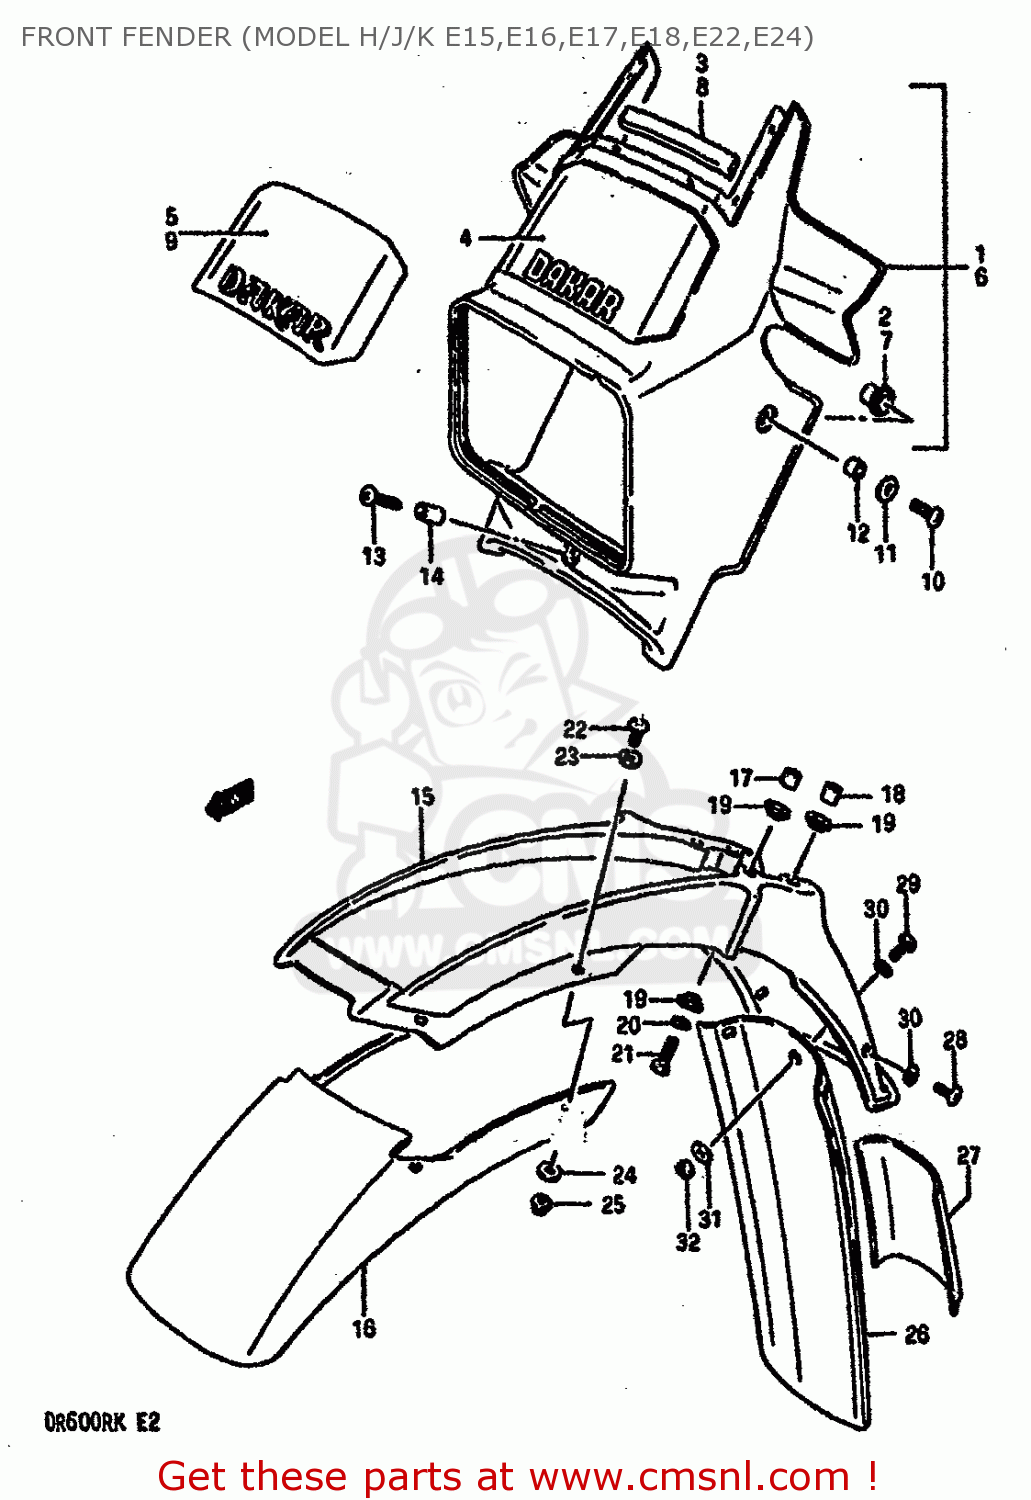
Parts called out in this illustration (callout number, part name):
1	COVER,HEADLAMP (WHITE)
2	BUSH, SIDE (WHITE)
3	CUSHION,HEADLAMP COVER
4	TAPE, HEADLAMP COVER
5	TAPE,HEADLAMP COVER
6	HOUSING ASSEMBLY,HEADLAMP
7	BUSHING,HEADLAMP COVER,SIDE
8	CUSHION,HEADLAMP COVER
9	TAPE,HEADLAMP COVER
10	SCREW
11	WASHER
12	SPACER
13	SCREW, LOWER
14	SPACER (6.1X9X31.5)
15	FENDER, FRONT REAR (WHITE)
16	FENDER,FRONT (BLUE)
17	SPACER(6.1X9X7.5)
18	SPACER (6.8X10X10)
19	WASHER
20	WASHER,LOCK
21	BOLT
22	SCREW
23	WASHER (6.5X18X1.6)
24	WASHER (6.7X16X1.8)
25	NUT
26	MUD FLAP, FRONT FENDER
27	PROTECTOR SEAT
28	SCREW
29	SCREW, CENTER
30	WASHER,LOCK
31	WASHER (6.7X16X1.8)
32	NUT 6MM
